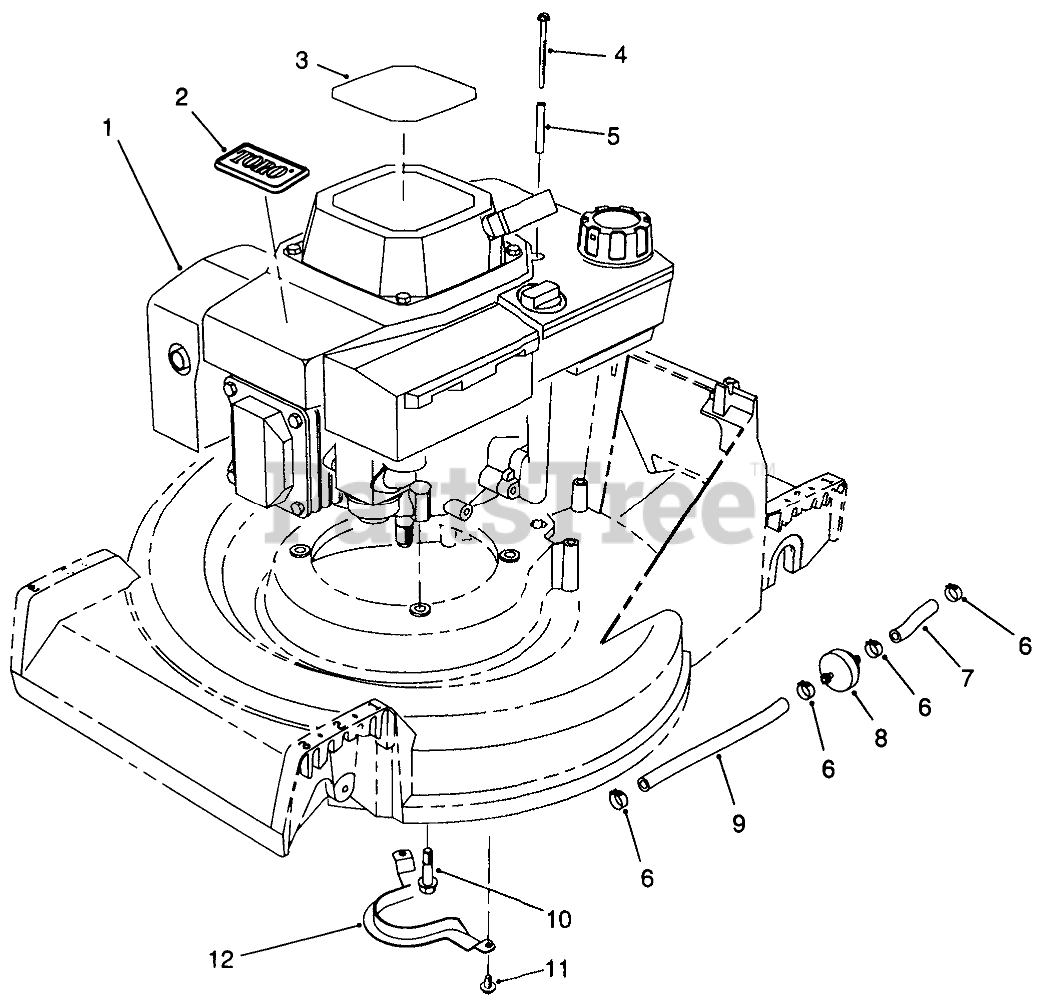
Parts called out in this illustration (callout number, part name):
1	ENGINE ASSY BBC OHV SU
2	TORO LOGO PLT
3	DECAL-HV INT'L
4	THRD FORMING SCREW
5	TUBULAR SPACER
6	CLAMP-FUEL LINE
7	LINE-GAS
8	FILTER-FUEL
9	HOSE-FUEL
10	SCREW-HWHTF
11	SCREW-HWHTF
12	Guide-Belt
